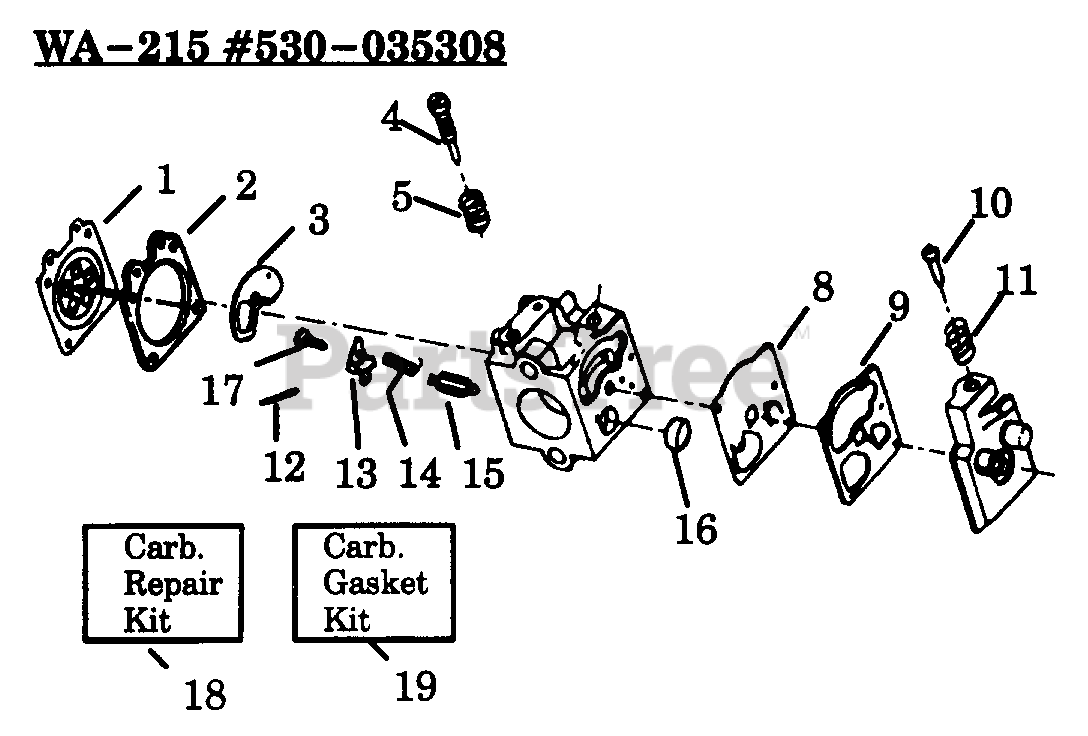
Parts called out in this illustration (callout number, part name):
1	Metering Diaphram
2	Metering Diaphragm Gasket
3	Circuit Plate Gasket
4	Mixture Needle
5	Mixture Needle Spring
8	Fuel Pump Diaphragm
9	Fuel Pump Gasket
10	Idle Speed Screw
11	Idle Speed Spring
12	Metering Lever Pin
13	Metering Lever
14	Metering Lever Spring
15	Inlet Needle Valve
16	Fuel Inlet Screen
17	Metering Lever Pin Screw
18	Carb. Kwik Repair Kit (Inc. 1,2,3,8,9,12, 13,14,15,16,17)
19	Carb. Gasket/Diaphragm Kit (Inc. 1,2,3,8,9)
